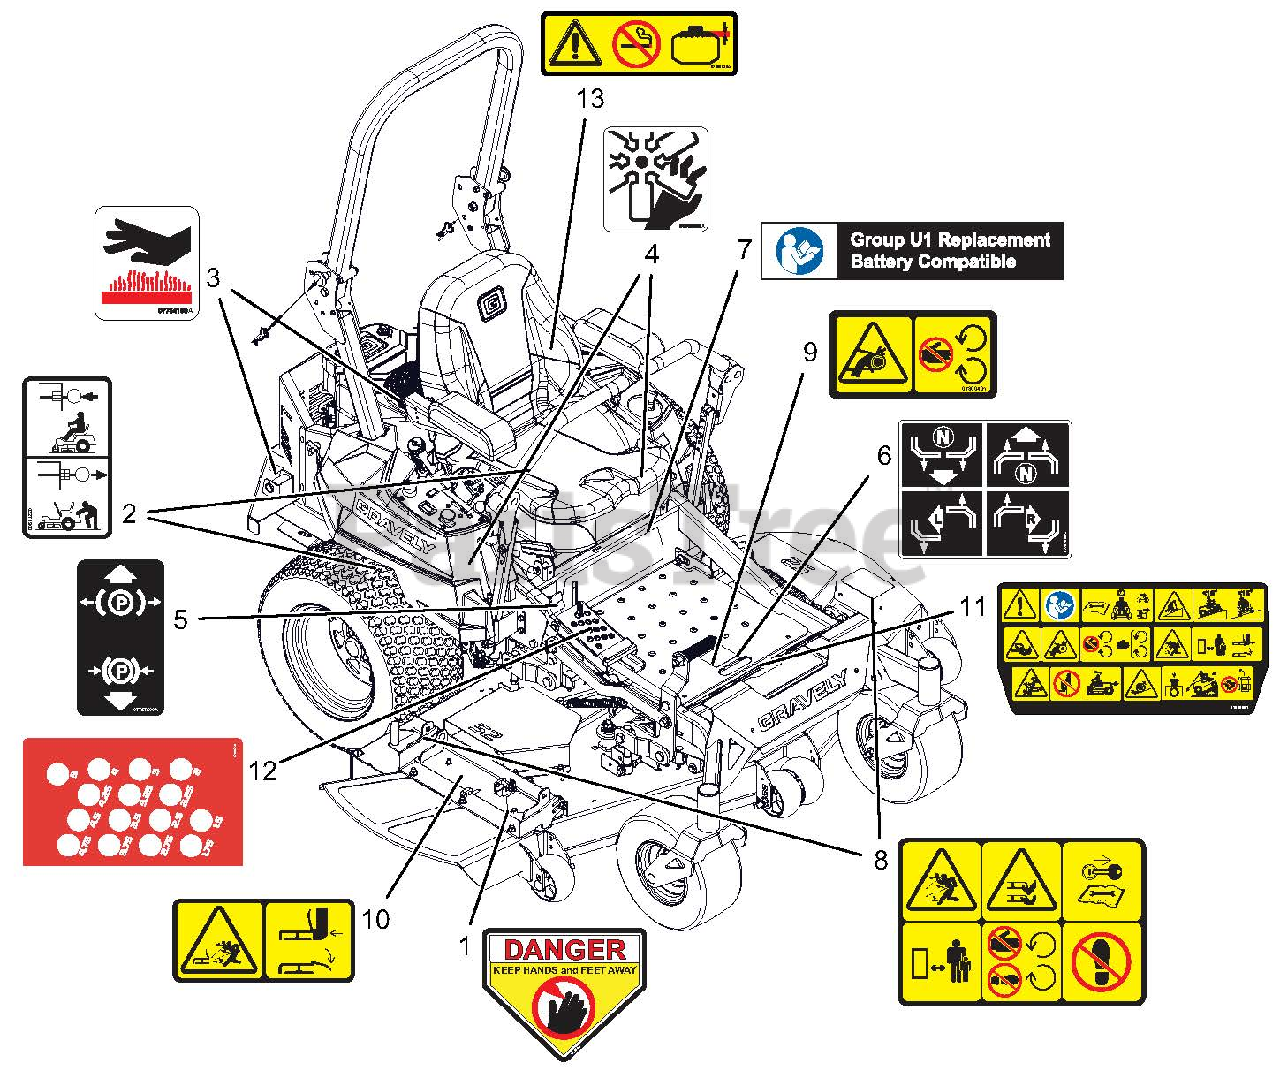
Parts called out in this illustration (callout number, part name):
1	DECAL, DANGER
2	DECAL, TRANSMISSION DISCONNECT
3	DECAL, HOT SURFACE
4	DECAL, DANGER FAN
5	DECAL, PARKING BRAKE LEVER
6	DECAL, INSTRUCTIONAL-STEERING
7	DECAL, U1 BATTERY REPLACEMENT
8	DECAL, SAFETY - MOWER DECK
9	DECAL, SAFETY - GUARDING
10	DECAL, SAFETY - DECK GUARDING
11	DECAL, MAIN SAFETY
12	DECAL - HOC
13	DECAL, FUEL WARNING
